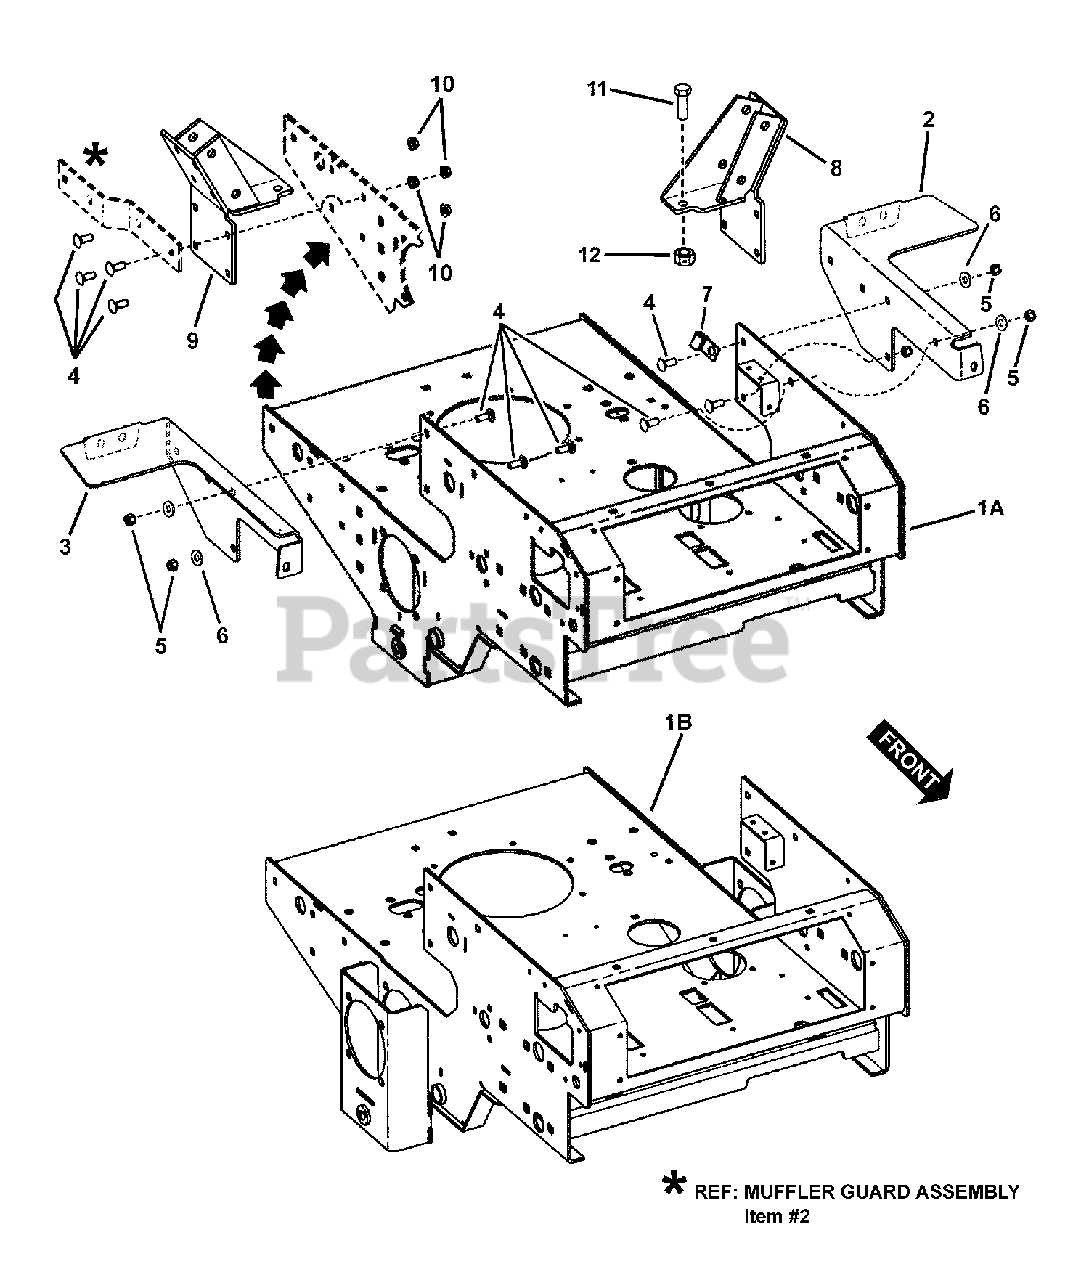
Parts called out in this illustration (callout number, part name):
1A	WELDMENT, Rear Frame (52" Deck)
1B	WELDMENT, Rear Frame (61" Deck)
2	WELDMENT, Left Hand Fuel Tank Bracket
3	WELDMENT, Right Hand Fuel Tank Bracket
4	BOLT, 3/8-16 x 1" Square Neck Carriage GR 5
5	NUT, 3/8-16 HEX NYLON LOCK
6	WASHER, 3/8" Flat
7	CLIP, Open 3/8" Cushioned
8	WELDMENT, Right Hand Socket
9	WELDMENT, Left Hand Socket
10	NUT, 3/8-16 HEX SERRATED FLANGE
11	BOLT, 1/2-13 X 1-1/2 GD5 CZ
12	NUT, 1/2-13 HEX SIDE LOCK
